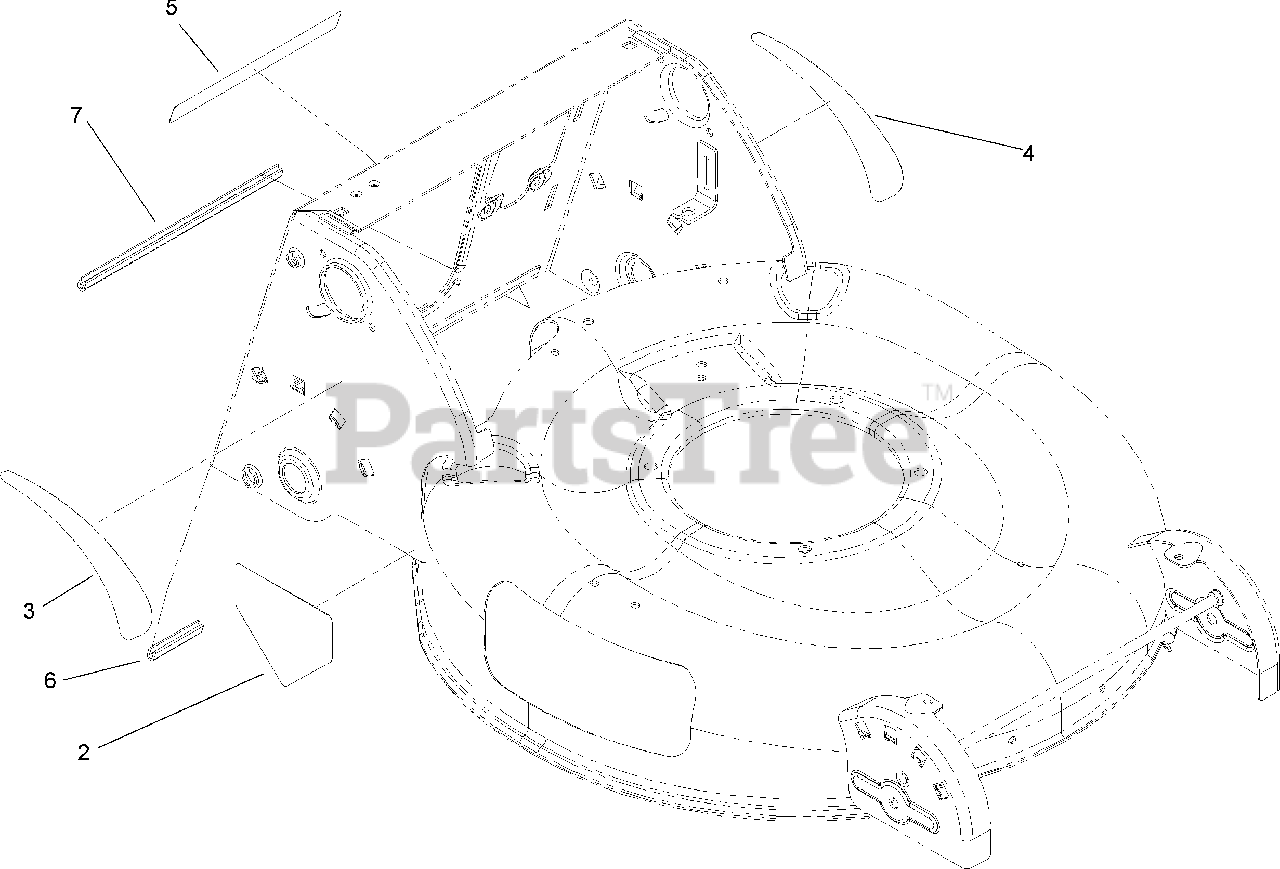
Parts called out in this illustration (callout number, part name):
2	DECAL-DANGER
3	DECAL-HOC, RH
4	DECAL-HOC, LH
5	DECAL-SAFETY
6	STRIP-EDGE
7	STRIP-EDGE
